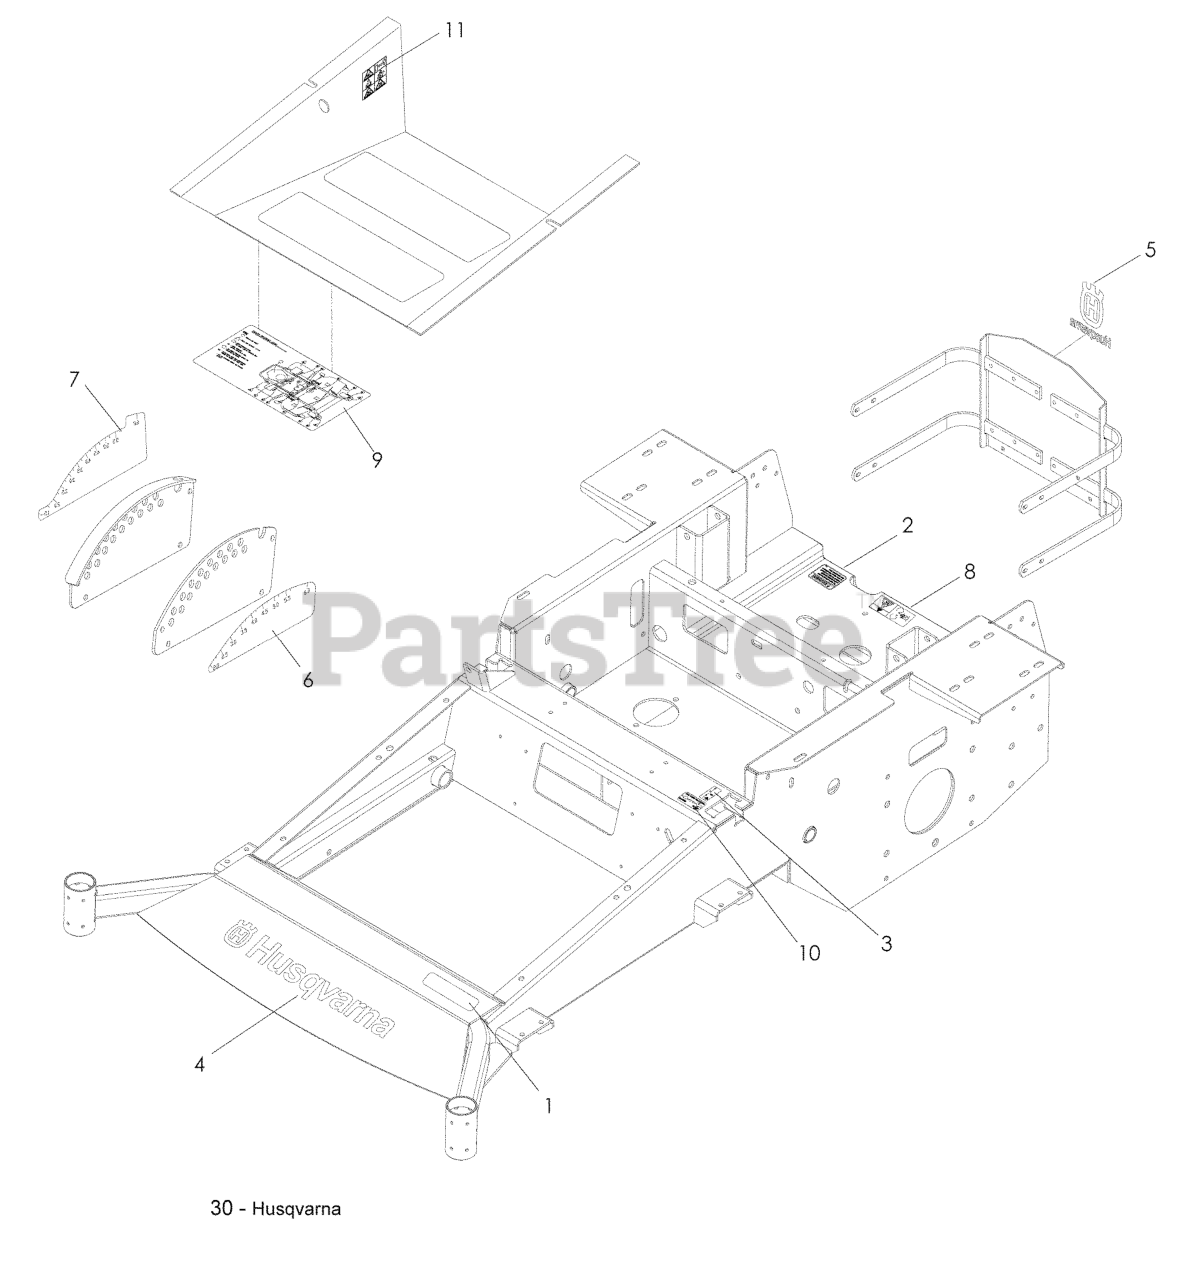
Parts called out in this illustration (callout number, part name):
1	DECAL, LZ5225
2	DECAL, PROP. 65
3	DECAL, MOTION CONTROL
4	DECAL, HUSQ 15" BLUE
5	DECAL, CROWN H 5-1/4 SILVER
6	DECAL, HEIGHT
7	DECAL, HEIGHT
8	DECAL, BELT DRIVE
9	DECAL, SERVICE
10	DECAL, F.S.T.
11	DECAL, WARNING
